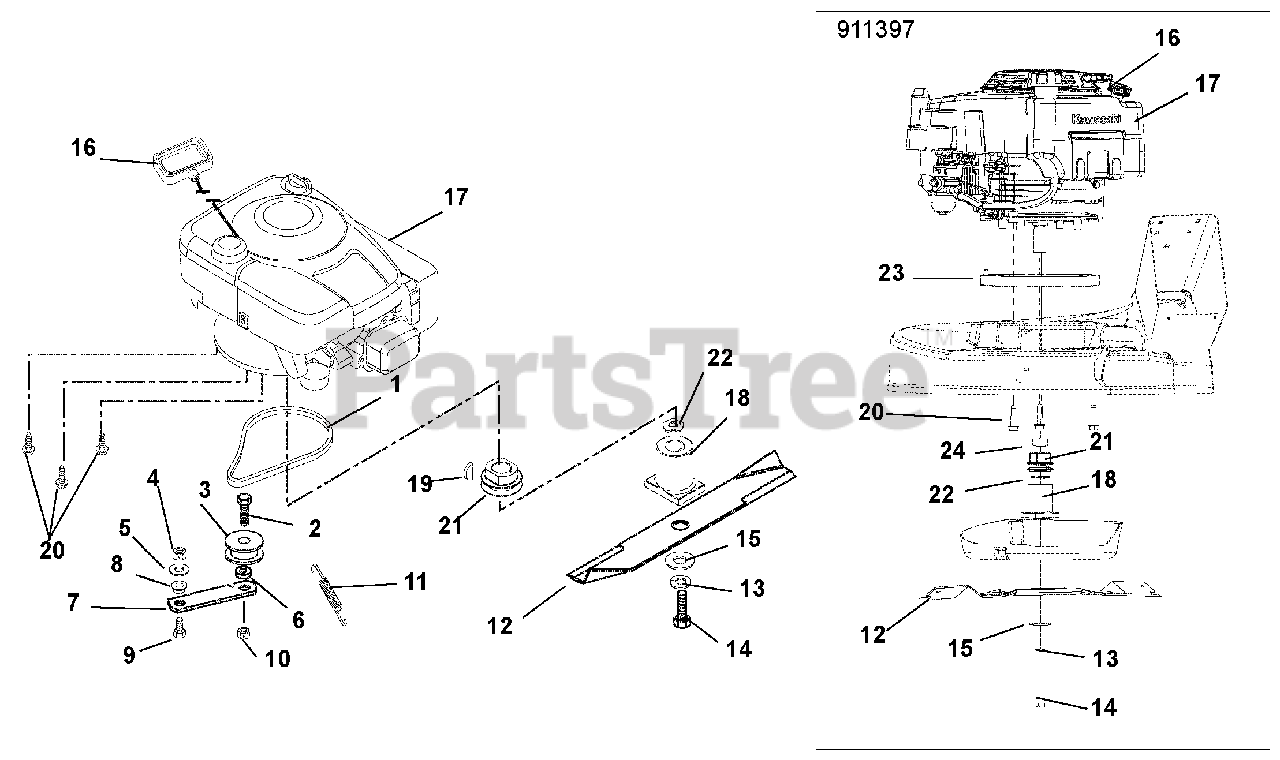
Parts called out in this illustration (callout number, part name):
1	V-BELT, 3L-COGGED
2	@BLT-HEX .44-14X1.50 GR5 YWZC
3	IDLER-FLAT 1.75 X .47
4	@NUT-LK-CTR .31-18 YWZC
5	@WSHR-FL-STL.344X.688X.065YWZC
6	BSHG-SLV .469 X .750 X .430
7	IDLER ARM
8	BSHG-FLG .325X.501X.250X1.120
9	@BLT-HEX .31-18X.75 GR5 YWZC
10	@NUT-LK-CTR .44-14 YWZC
11	SG-TENS .043X.44X3.31 WLD 5.8
12	BLADE, 21" LM MULCHING
13	@WSHR-LK .38X.094 REG YWZC
14	BLT-HEX .38-24 X 2.00 GR8 YWZC
14	BLT-HEX .38-24 X 2.75 GR8 YWZC
15	WSHR-FL-STL .390X1.5X.125 YWZC
16	HANDLE, RECOIL START
17	B&S - 6.5 HP DOV
17	ENGINE,KAWI FJ180 PRO-50 STATE
18	ADAPTER, CE BLADE
18	ADAPTER, BLADE - KAWI KYMCO
19	KEY-WDRF .156X.625X.25 SAE 6
20	@SCR-TAP .38-16X1.00 HWH TR YZ
20	@SCR-TAP .38-16X1.75 HWH TR YZ
21	PULLEY-SINTERED IRON LM
21	PULLEY, CRANK - KAWI KYMCO
22	WASHER-WAVE .885X1.311X.125
23	PLATE, ENGINE SHIM - CAST
24	SPACER, .875 X 1.125 X .525
25	SHIM, DOV CE LM ENGINE
26	SPACER,.75 X .515 X .12
